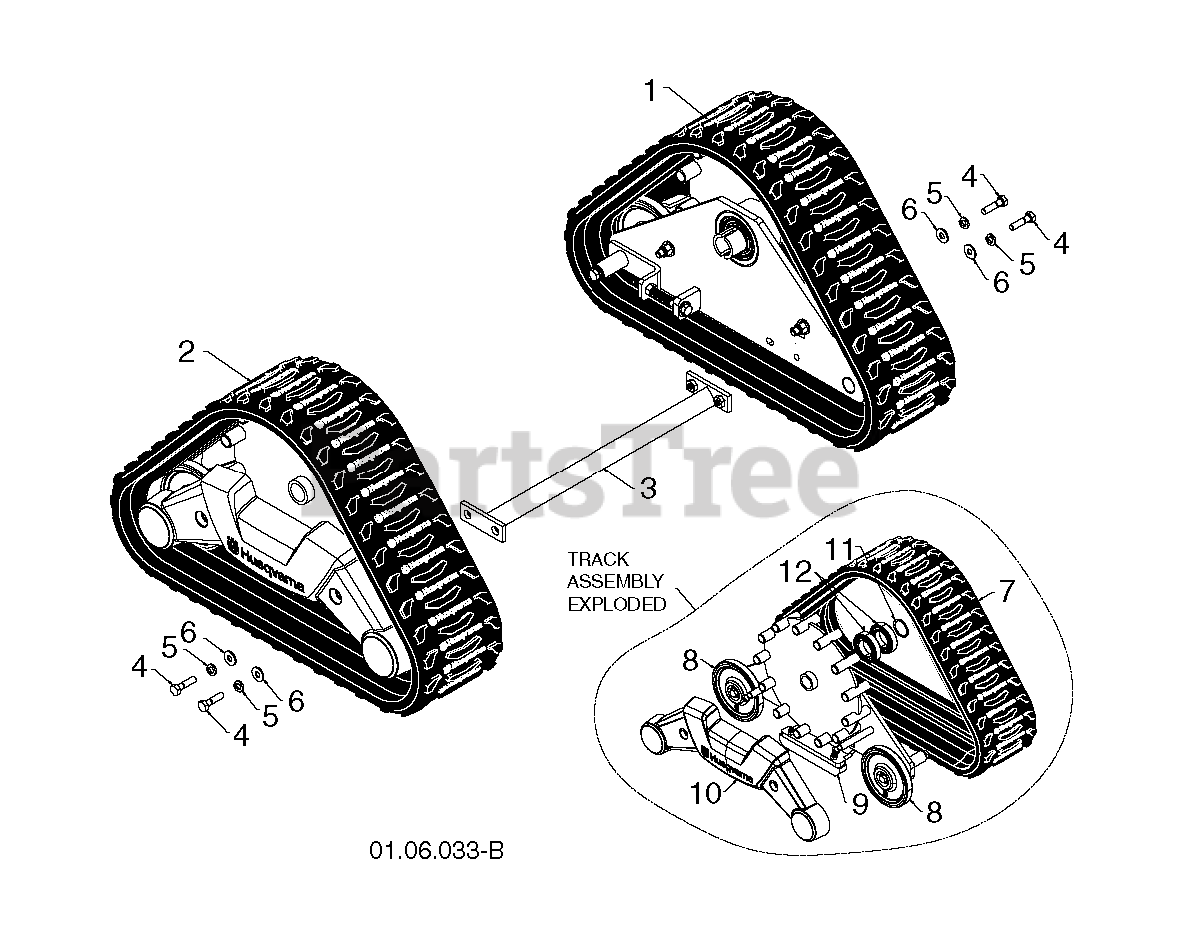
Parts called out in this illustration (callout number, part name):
1	WHEEL.ASM.TRACK.LH.SNOW
2	WHEEL.ASM.TRACK.RH.SNOW
3	SUPPORT.BRACE.ASM.TRACK
4	BOLT.5/16-18X1-1/4 FULL.THREAD
5	WASHER.LOCK.HVY.HLCL.SPR.5/16
6	WASHER.20X8.5
7	BELT.TRACK.RUBBER.SNOW
8	IDLER.WHEEL.TRACK
9	SKID.TRACK.SNOW
10	COVER.SIDE.TRACK
12	BEARING.BALL.SHIELD.TRACK.SNOW
